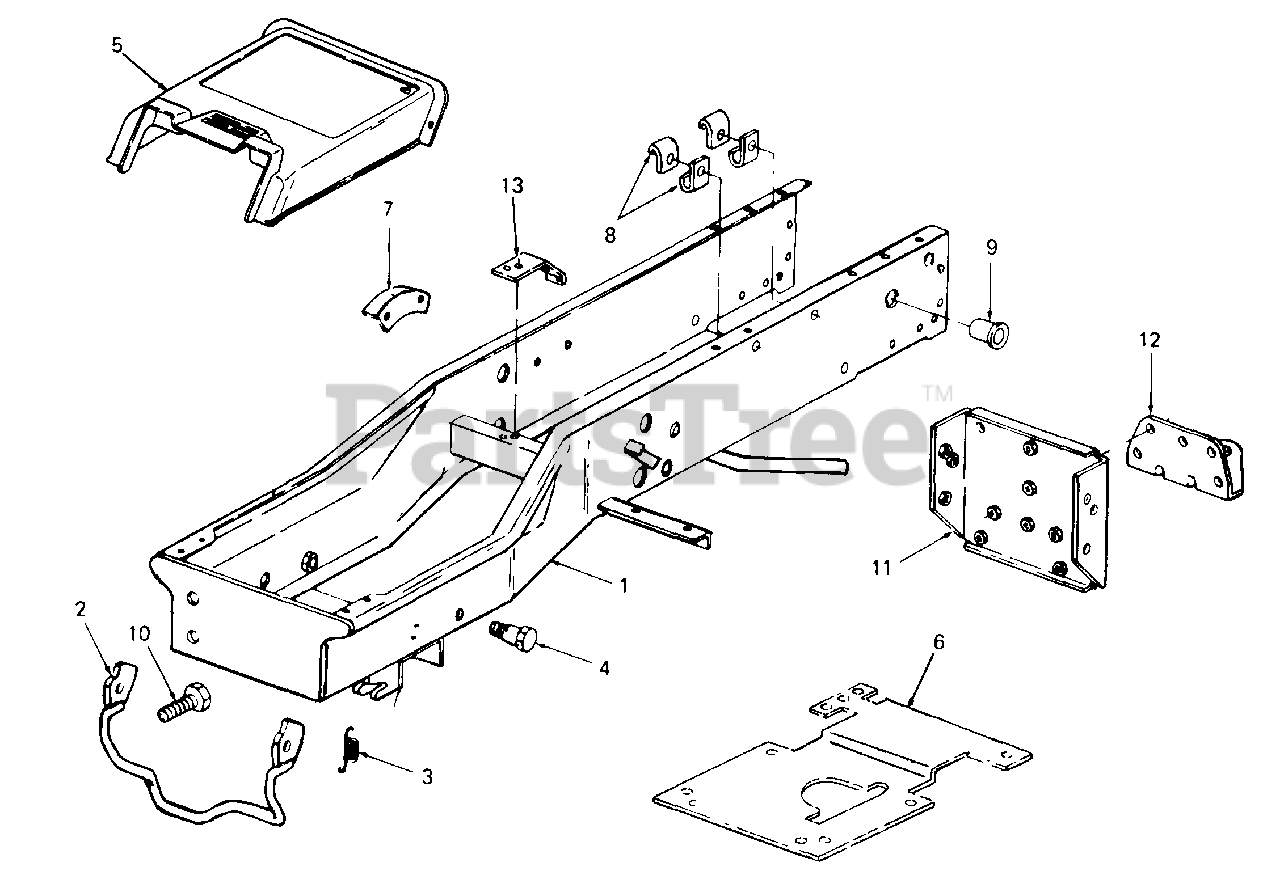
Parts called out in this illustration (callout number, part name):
3	Spring, Latch
4	Bolt, Shoulder
5	Cover, Frame
7	Bracket, Height Indicator
8	Clip, Cable
9	Bushing, Snap
10	Screw, Adjustment, 1/2-20 X 1.0 Lg GR5
13	Bracket, Switch
